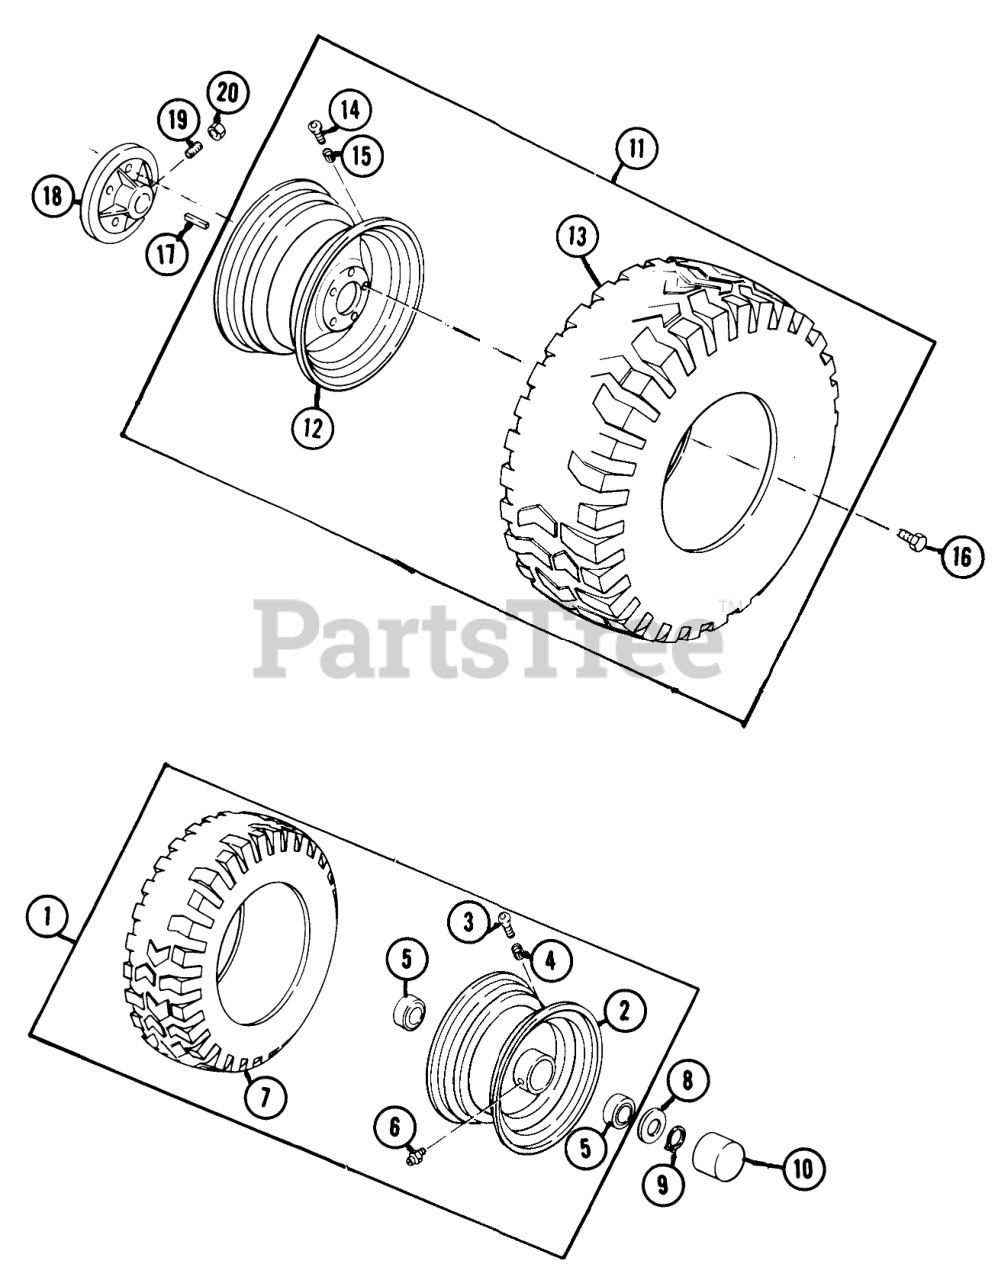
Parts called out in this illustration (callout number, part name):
13-01	Wheel & Tire Assembly, Front
13-02	Wheel, Front
13-03	Valve
13-04	Cap, Valve
13-05	Bearing, Front Wheel
13-06	Grease Fitting
13-07	Tire, Front
13-08	Washer-3/4
13-09	Snap Ring
13-10	DUST CAP
13-11	Wheel & Tire Assembly, Rear
13-12	Wheel, Rear
13-13	Tire, 23 x 8.50-12, Rear
13-14	Valve
13-15	Cap, Valve
13-16	Wheel Lug
13-17	Woodruff Key 1/4 x 1/8
13-18	Hub
13-19	Set Screw Sq. Hd. 5/16-18 x 1
13-20	Nut, Hex Jam 5/16-18
